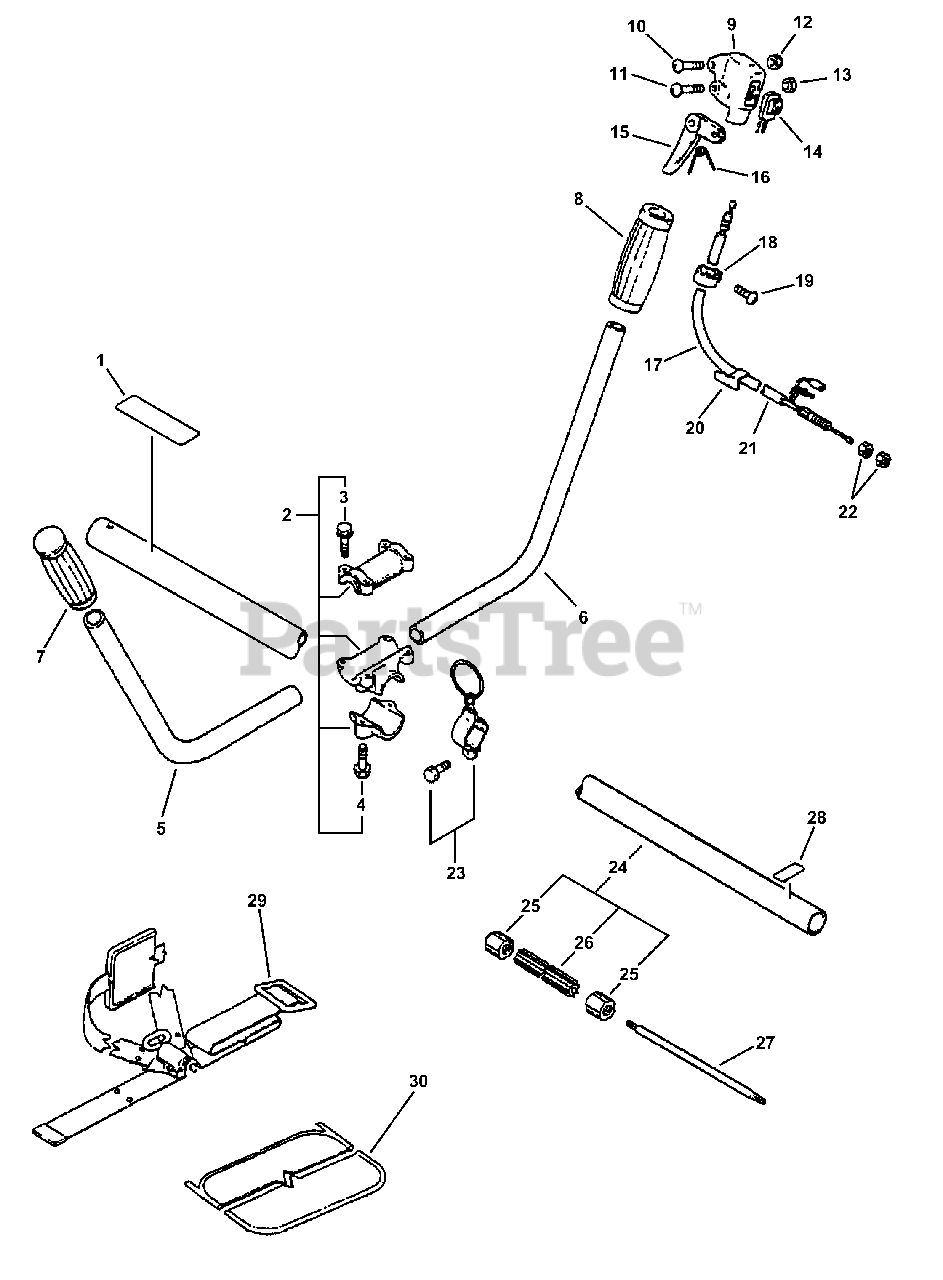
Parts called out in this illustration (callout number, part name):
1	LABEL, CAUTION
2	HANDLE BRACKET KIT
3	BOLT - 5×25
4	BOLT - 6×30
5	HANDLE, LEFT
7	GRIP, HANDLE
9	BRACKET, THROTTLE
10	SCREW 5×25
12	NUT, LOCK M5
13	NUT M5
14	IGNITION SWITCH ASSY
15	TRIGGER, THROTTLE
17	CABLE, THROTTLE
19	SCREW 5×10
21	TUBE
23	HOOK
24	MAIN PIPE ASSY 25×1500
26	LINER, FLEXIBLE 21.6×1420
27	DRIVESHAFT - FLEXIBLE L= 1522
28	LABEL - ALIGNMENT
29	SHOULDER STRAP ASSY
30	PAD, HIP
